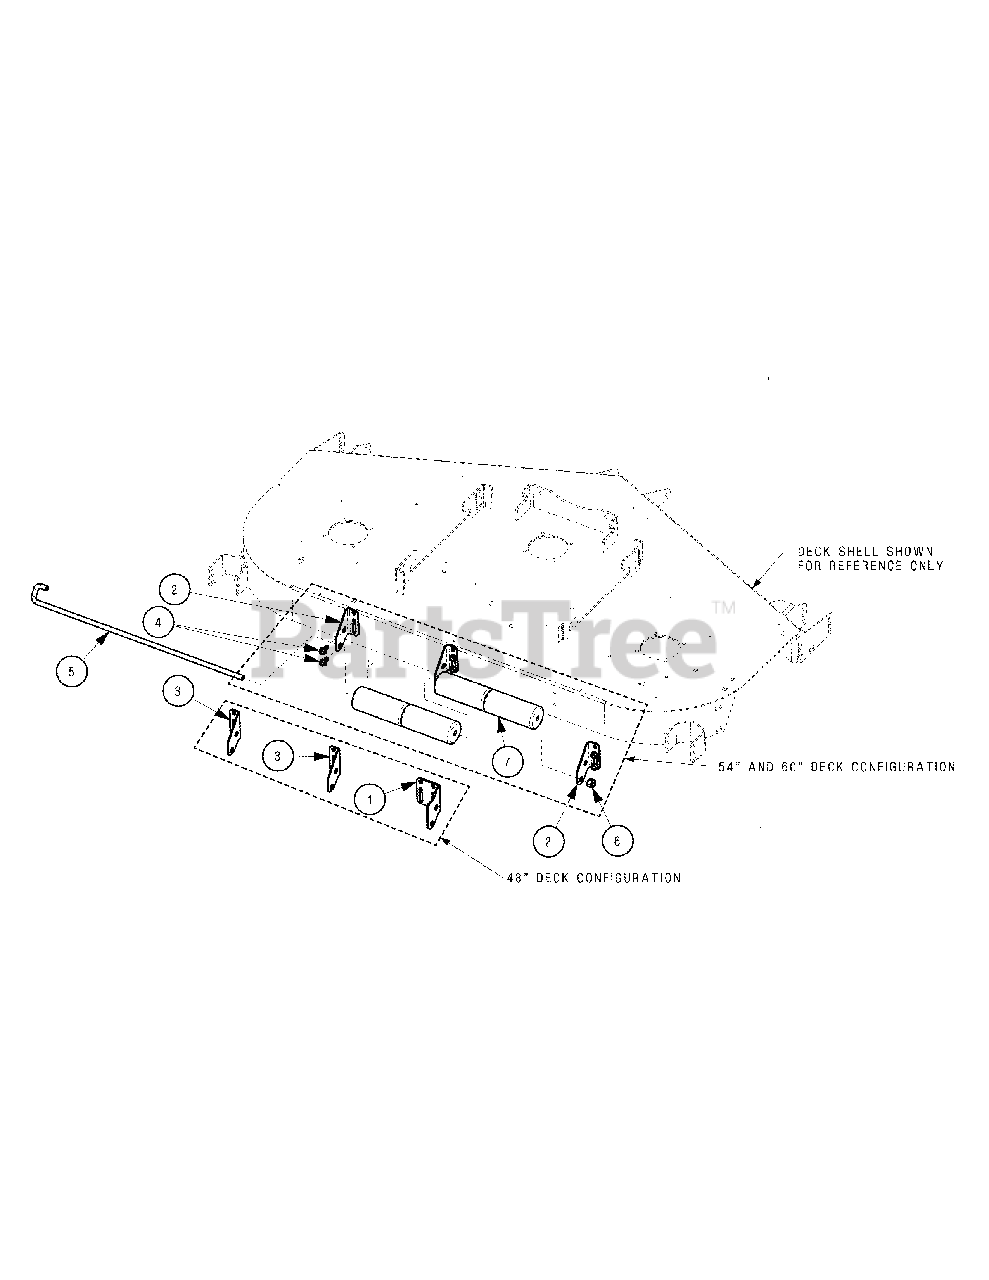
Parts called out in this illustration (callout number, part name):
1	Roller Mount Bracket 48"
2	Roller Mount Bracket
3	Roller Mount Bracket 48"
4	Hex Washer Head Screw, 3/8 -16 x .75
5	J-Hook w/ Threaded Roller
6	Nut, Hex Lock, 1/2-13, Gr8, Nylon
